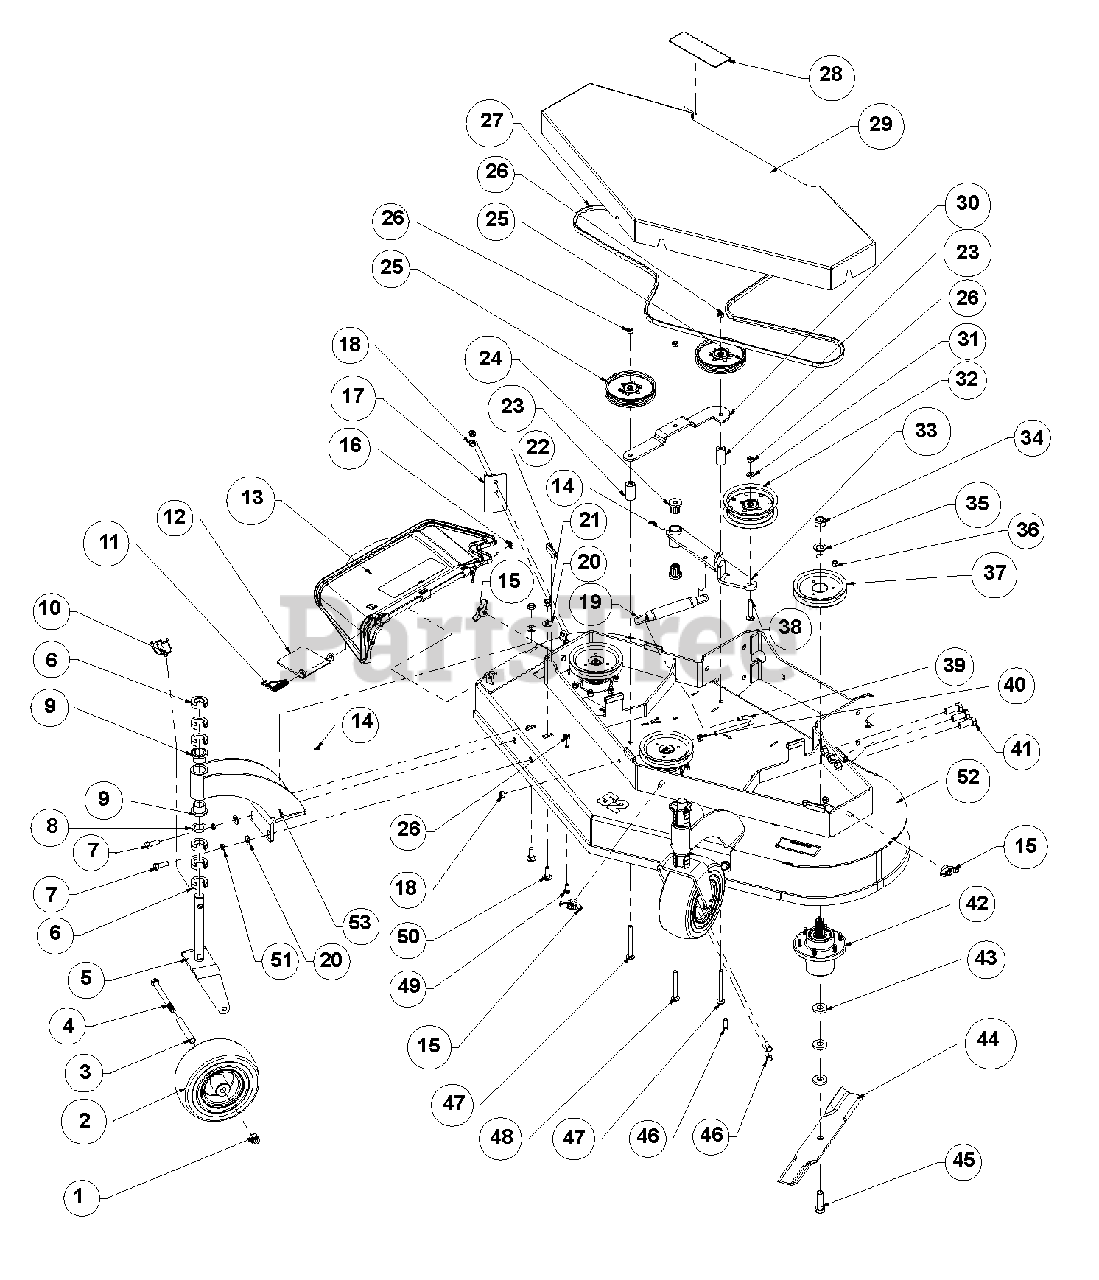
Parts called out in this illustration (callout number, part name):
1	Locknut, .50-13 Nyloc
2	Assembly, Wheel and Tire 9 x 3.5
3	Tube, Caster Axle
4	Bolt, .50-13 x 5.50 Hex 5
5	Weldment, Caster Yoke W/Gravely Paint
6	C-Spacer, 1.00 x 1.77 x .500
7	Bolt, .4375-14 x 1.25 Hex 5
8	Bushing, 1.03 x 1.50 x .179
9	Bearing, Flange 1.00 x 1.25 x 1.00
10	Pin, LNC .438 x 2.00
11	Spring, Discharge Chute
12	Bracket, Chute Support
13	Chute, Discharge Assembly
14	Fitting, .25-28 Straight Grease Zerk
15	Knob, .38-16 Insert
16	Retainer
17	Plate, Extender
18	Locknut, 3/8-16 Nyloc
19	Spring, External
20	Washer, .375 Regular Flat
21	Locknut, .4375-14 Crown
22	Trim, 1/4" Trim-Lok Edge
23	Spacer Assembly
24	Bearing, Flange M10 x M25 x M27 Fluted
25	Pulley, Flat Idler
26	Locknut, .38-16 Crown
27	Belt, HB 109.3 Elbow AMD
28	Decal, Pro-1952
29	Weldment, 52" Belt Shield Gravely
30	Strap, Idler Pulley Hydro Walk
31	Washer, .406 x .813 x .065 Flat
32	Pulley, Flat 5.00 x .375 W/BRG
33	Arm, Idler
34	Locknut, .75-16 Crown
35	Washer, .75 x 1.3125 x .120
36	Nut, .38-16 Standard Hex 5
37	Pulley, Spline Spindle LSE
38	Bolt, .38-16 x 2.25 Round Head Square Neck
39	J-Bolt, .38-16 x 4.00
40	Locknut, .38-16 WHIZ
41	Bolt, Hex .6250-11 1.5" Grade 8
42	Assembly, Spindle Housing
43	Washer, .630 x 1.50 x .250 Flat
44	Blade, 18.000 x .80 Lift
45	Bolt, .625-11 x 2.00 Hex 8
46	Bolt, .38-16 x 1.00 Hex 5
47	Bolt, .3750 x 4 SHTNK Round Head Bolt
48	Bolt, .38-16 x 3.50 Round Head Square Neck
49	Bolt, .38-16 x .750 Hex 5
50	Bolt, .4375-14 x 1.25 Round Head Square Neck
51	Washer, .438 Medium Spring Lock
52	Assembly, 52" Gravely Deck w/Decals
53	Weldment, Caster Support w/Gravely Paint
